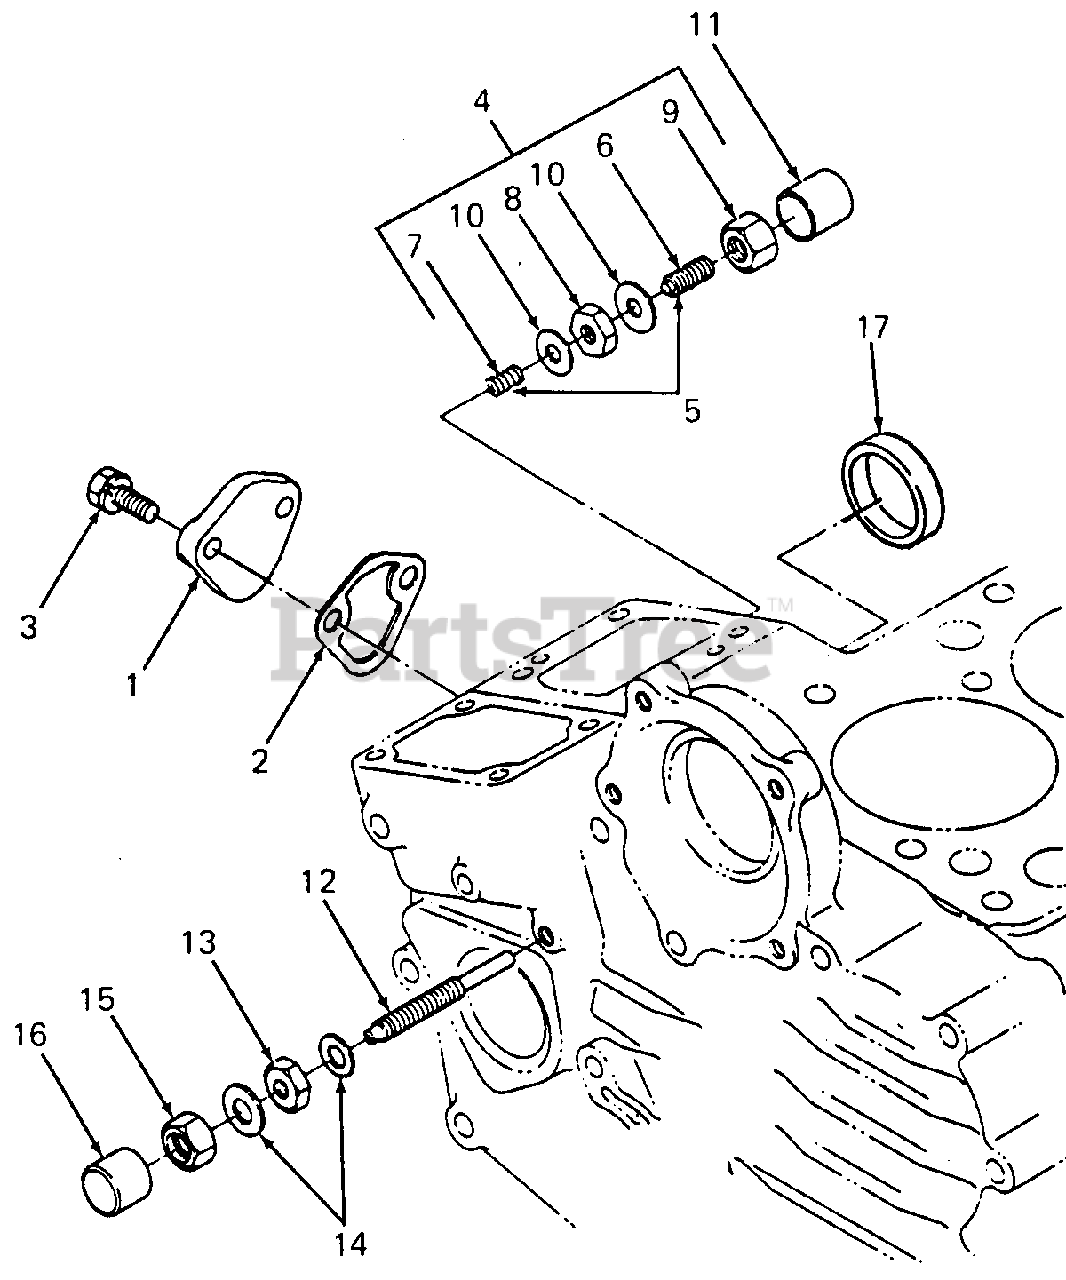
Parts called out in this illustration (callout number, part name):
3	Screw, Hex Cap w/Washer
4	Bolt Assy, Idling
5	Bolt Assy, Adjusting
12	Bolt, Adjusting
17	Cover
